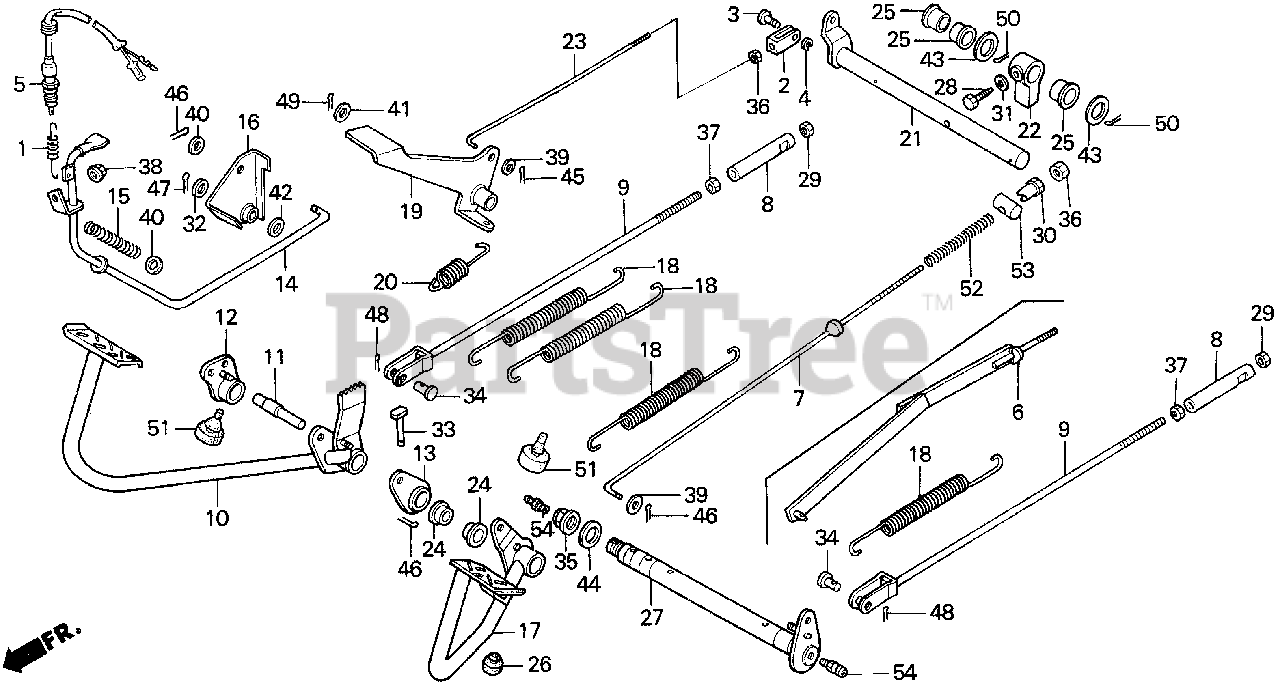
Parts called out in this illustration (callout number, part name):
1	SPRING, GOVERNOR
2	JOINT, PEDAL CHANGE
3	PIN, CHANGE PEDAL
4	E-CLIP (4MM)
5	SWITCH ASSY., PARKING BRAKE
7	ROD, CLUTCH
8	JOINT (8MM)
9	ROD, RR. BRAKE (B)
10	PEDAL, BRAKE
11	BAR, EQUALIZER
12	ARM, R. EQUALIZER
13	ARM, L. EQUALIZER
14	LEVER, PARKING BRAKE
15	SPRING, PARKING BRAKE LEVER
16	ARM, PARKING BRAKE STOPPER
17	PEDAL, CLUTCH
18	SPRING, CLUTCH PEDAL
19	PEDAL, DIFFERENTIAL LOCK
20	SPRING, DIFFERENTIAL LOCK PEDAL
21	ARM, DIFFERENTIAL LOCK
22	ARM, DIFFERENTIAL LOCK
23	ROD, DIFFERENTIAL LOCK CONTROL
24	BUSH, BRAKE PEDAL
25	BUSH, DIFFERENTIAL LOCK PEDAL
26	RUBBER B, STOPPER
27	SHAFT, BRAKE
28	BOLT, HEX. (8X24)
29	NUT, HEX. (8MM)
30	NUT, ADJUSTING
31	WASHER, CONICAL SPRING (8MM)
32	WASHER (12.2X26) (NOT AVAILABLE)
33	PIN, BRAKE SHAFT
34	PIN (8X17.5)
35	NUT, STEERING SHAFT
36	NUT, HEX. (6MM)
37	NUT, HEX. (8MM)
38	NUT, FLANGE (6MM)
39	WASHER, PLAIN (6MM)
40	WASHER, PLAIN (8MM)
41	WASHER, PLAIN (12MM)
42	WASHER, PLAIN (12MM)
43	WASHER, PLAIN (14MM)
44	WASHER, PLAIN (18MM)
45	PIN, COTTER (1.6X25)
46	PIN, SPLIT (2.0X15)
47	PIN, SPLIT (2.0X22)
47	PIN, SPLIT (2.0X35)
48	PIN, SPLIT (2.5X30)
49	PIN, SPLIT (2.5X30)
50	PIN, SPLIT (2.5X30)
51	RUBBER B, STAND STOPPER
52	SPRING A, BRAKE ROD
53	JOINT B, BRAKE ARM
54	NIPPLE, GREASE (A.T6) (M6X1.0)
